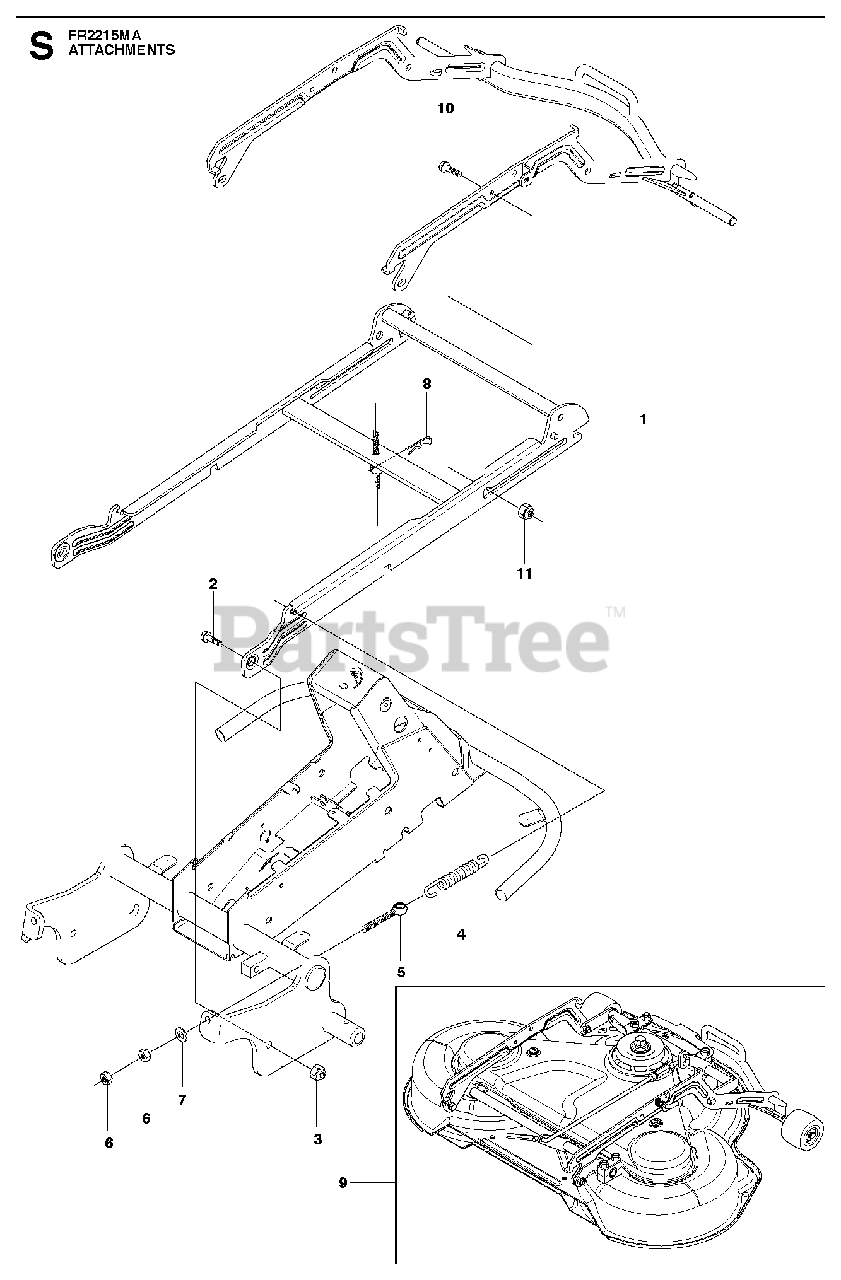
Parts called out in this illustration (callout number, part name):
7	WASHER
10	COLLAR SCREW
11	LOCKNUT M8
